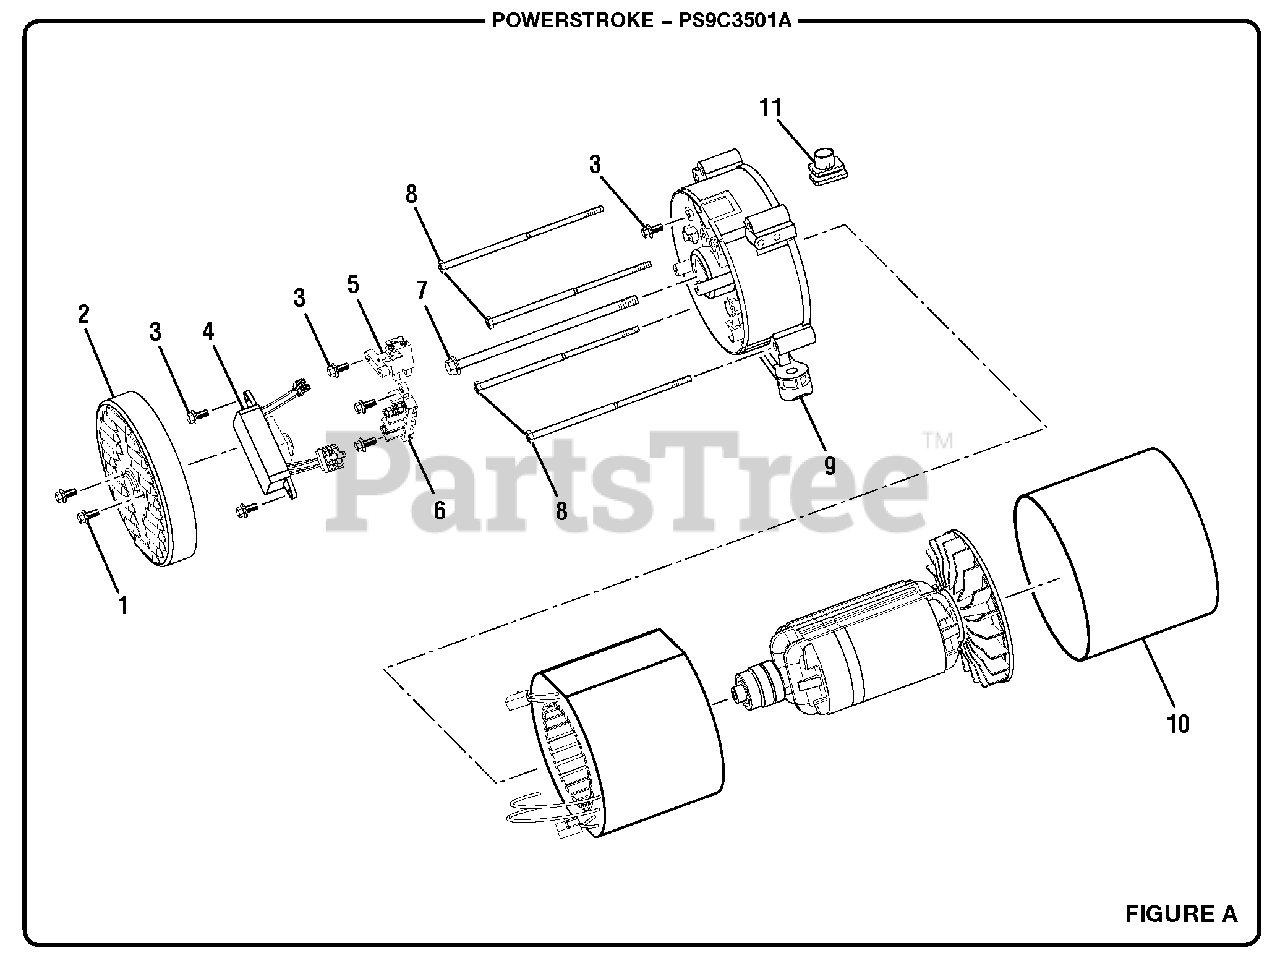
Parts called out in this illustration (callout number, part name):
1	Bolt (M5 x 16 mm, Hex Hd.)
2	Brush Cover
3	Bolt (M5 x 10 mm)
4	Automatic Voltage Regulator
5	Brush Assembly
6	Terminal Block
7	Rotor Bolt
8	Stator Bolt
9	Bearing Housing
10	Generator Head Cover
11	Rubber Boot
